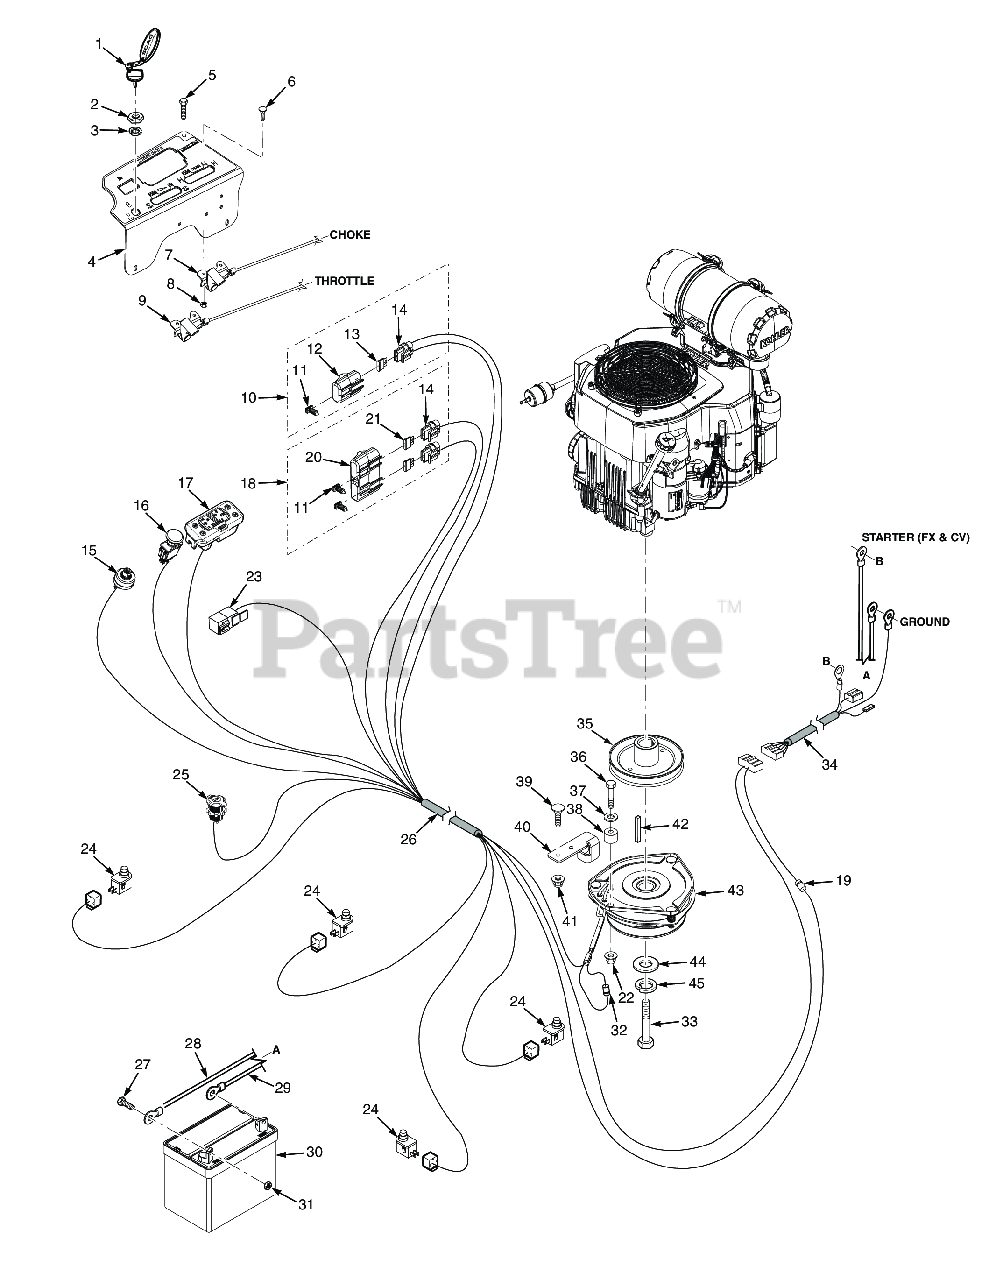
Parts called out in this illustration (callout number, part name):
1	Key, Ignition
2	Nut, 5/8-32 Special
3	LOCK WASHER, 5/8" INTERNAL TOOTH
4	Instrument Panel w/Decal
5	CAP SCREW, 1/4-20 X 1/2" SERRATED FLANGE HEX
6	Bolt, Carriage #10-24 x 1/2"
7	Throttle Control Cable (Kawasaki FS / FX, Kohler CV)
7	Choke Control Cable (Kohler CV)
8	Nut, Elastic Stop #10-24
9	Throttle Control Cable (Kawasaki FS / FX, Kohler CV)
10	Single Fuse Assy., Excluding Fuse
11	Clip, Fuse Holder
12	Cover, Sealed Single
13	Fuse, 5 Amp
14	Fuse Holder Assembly
15	KEY SWITCH(INCLUDES MOUNTING HARDWARE)
16	Switch, PTO - 10 Amp
17	Tiger Eye, Cluster Gauge
18	Double Fuse Assy.
19	Decal, Forward Speed Selector
20	Cover, Sealed Double
21	FUSE, 20 AMP BLADE TYPE AUTOMOTIVE
22	HEX NUT, ELASTIC STOP LOCK, 5/16-18
23	Relay, 12V 40 AMP Standard
24	Switch, Interlock, Normally Open
25	Power Plug, 12V
26	Wire Harness
27	Bolt, Hex Head 1/4-20 x .5" Battery, (Not Available Through Scag)
28	Battery Cable, 25" Red
29	Battery Cable, 27" Black (35BV & 37BV-EFI) - Briggs & Stratton
30	Battery, 350 CCA
31	Nut, 1/4 - 20 Hex
32	Diode, 600V 6 Amp
33	Bolt, Hex Head 7/16-20 x 2-3/4" w/ Patch
34	Wire Harness Adapter, Kawasaki - 22FX & 23FX
34	Wire Harness Adapter, Kohler - 23CV
35	Pulley, 5.75" Dia. - 1.125 Bore
36	Bolt, Hex Head 5/16-18 x 2-1/2" (x3) (35BV & 37BV-EFI)
37	Flatwasher, 5/16-.375 x .875 x .083 (35BV & 37BV-EFI)
38	BUSHING, UHMW
39	Bolt, 5/16-18 x .75 RHSN Carriage
40	ANTI ROTATION
41	Nut, Flange Head Elastic Stop 5/16-18
42	Key, 1/4 x 1/4 x 3-1/2"
43	Clutch w/Tag GT3.5--FE05 (61)
44	Flatwasher, 7/16-.469 x 1.75 x .25 (48, 52)
45	Lockwasher, 7/16� Spring
